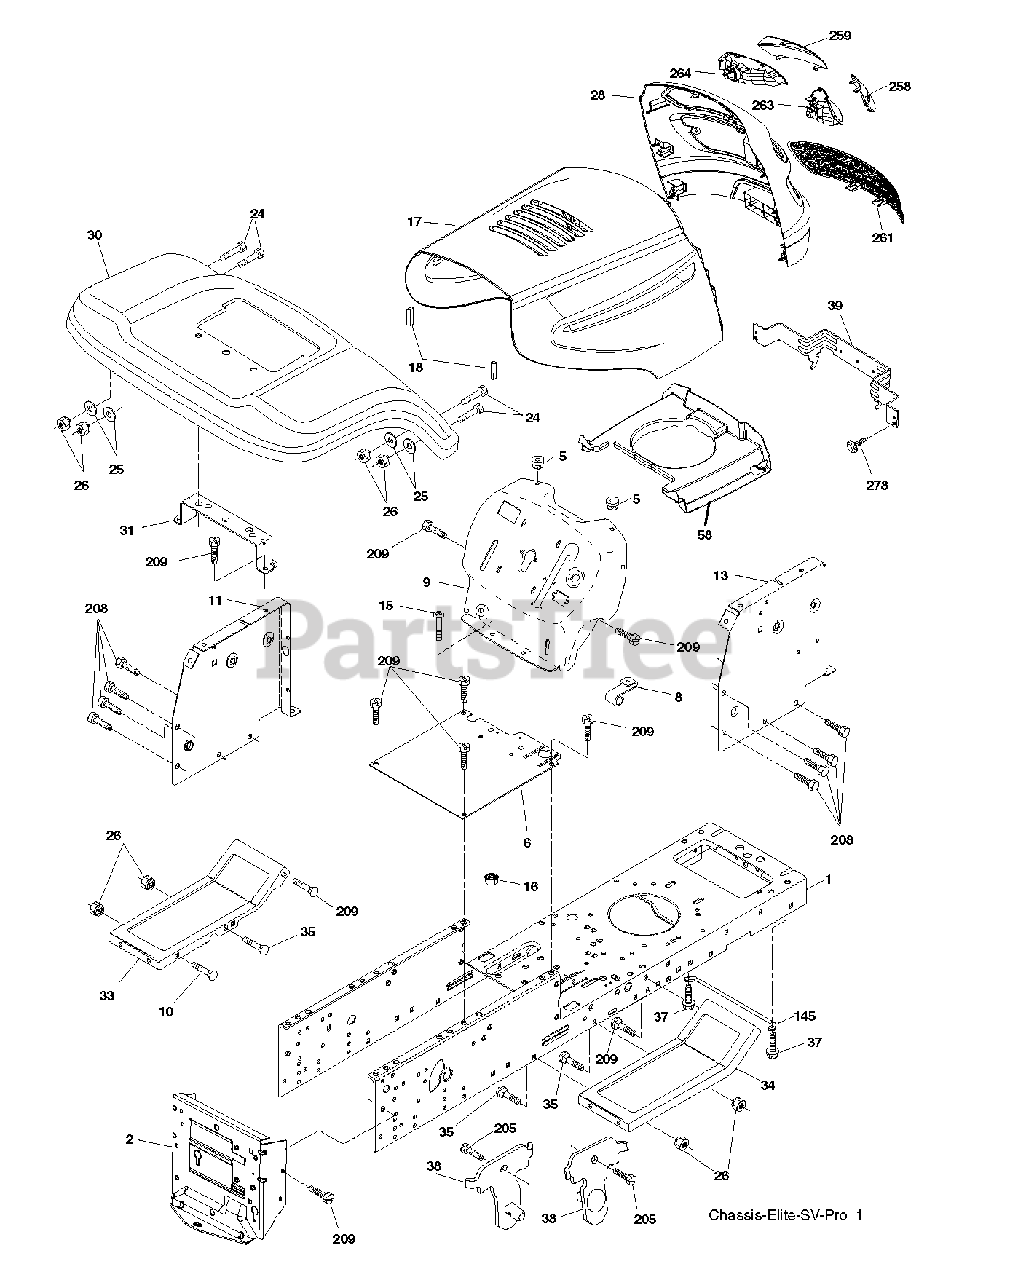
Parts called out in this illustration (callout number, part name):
1	CHASSIS
2	DRAWBAR, 12GA
5	BUMPER.RUBBER.HOOD
8	CLIP RETAINER
9	FENDER LT SH
10	BOLT D
11	PANEL.DASH.LH.LTX
13	PANEL.WELDMENT.DASH.R
16	NUT
17	HOOD.STEEL.ELITE.-SV.PRO.667
18	BUMPER.HOOD.LARGE.1.75"
25	WASHER
26	NUT
30	FENDER.PNT.LT.W/SFT.W/OCUP.667
31	BRACKET FENDER
33	FOOTREST.PNT.LH.MS667
34	FOOTREST.PNT.RH.MS667
38	BRACKET.ASM.PIVOT.MOWER.REAR
39	BRACKET PIVOT
145	ROD.PIVOT.HOOD
208	SCREW 3/8-16X1/2
209	SCREW, 3/8-16X3/4
258	Grille Lens, Pro RH Clear
263	BEZEL GRILL RH
264	BEZEL GRILL LH
278	SCREW.#10 X 0.750.BOS THREAD
